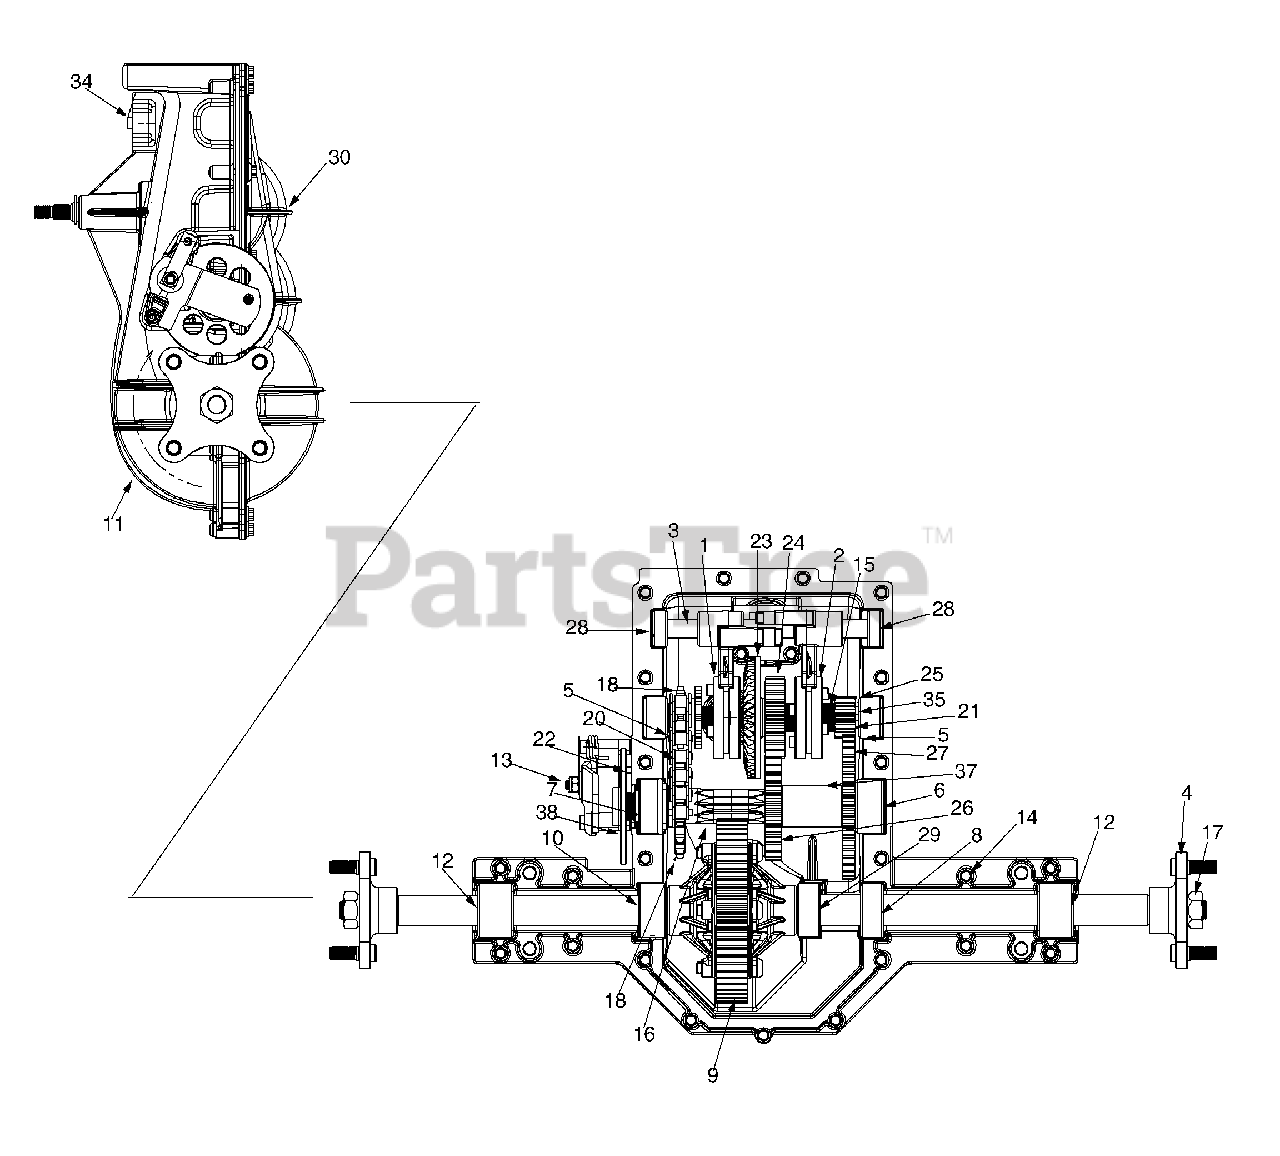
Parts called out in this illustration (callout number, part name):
1	Collar Ass'y.- Reverse
2	Collar Ass'y.- Hi-Lo
3	Shift Fork Ass'y.
4	Wheel Hub Ass'y.
5	Drive Shaft Blk. Ass'y.
6	Output Brg. Blk. Ass'y.
7	Output Brg. Blk. Ass'y. Seal
8	Inboard Axle Blk. Ass'y.
9	Differential Axle Ass'y.
10	Inboard Axle Blk. Ass'y.
11	Upper Housing Ass'y.
12	Axle Brg. Blk. Ass'y.
13	Bracket Ass'y.- R.H.
14	Hex Wash. TT-Tap Scr. 1/4-20 x 1"
15	Drive Shaft
16	Output Shaft - R.H.
17	Hex Nut 3/4-16
18	Sprocket 9T
20	Chain Endless
21	Ext. Snap Ring
22	Brake Pad
23	Bevel Gear 41T
24	Spur Gear 20T
25	Spur Gear 10T
26	Spur Gear 27T
27	Spur Gear 37T
28	Shifter Brg. Blk.
29	Inner Axle Blk. Brg.
30	Lower Housing
34	Shipping Plug
35	Fl-Wash. 5/8" I.D. x 1" O.D.
37	Spacer 1.13" I.D. x 1.38" O.D.
38	Disc Brake
